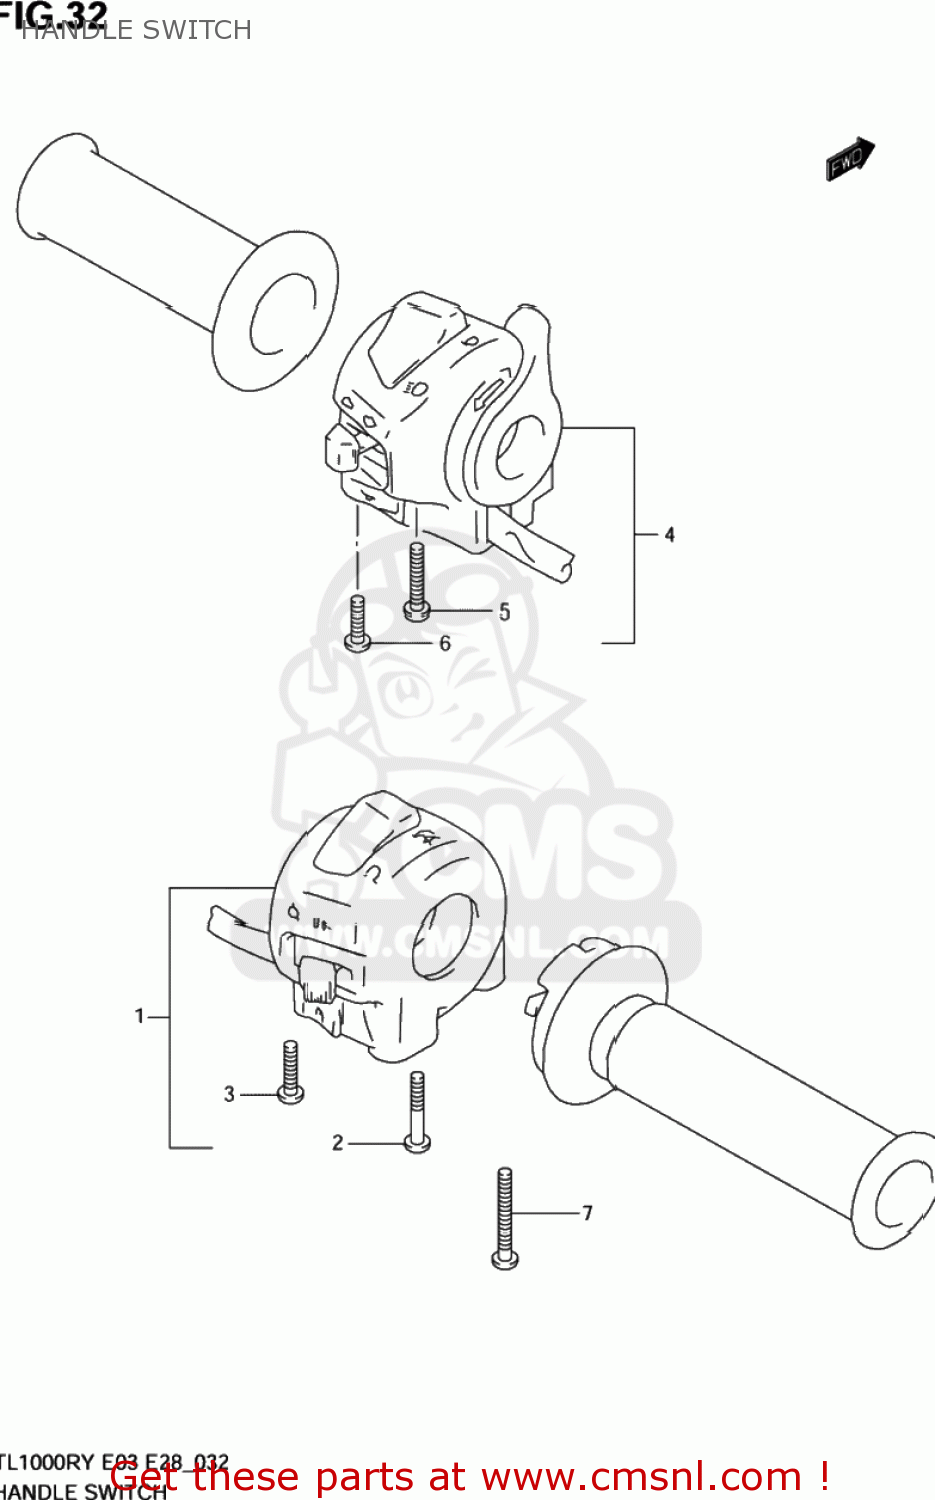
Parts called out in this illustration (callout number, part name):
1	SWITCH ASSY,HANDLE,R
2	SCREW
3	SCREW
4	SWITCH ASSY,HANDLE,L
5	SCREW
6	SCREW, 5X45
7	SCREW
